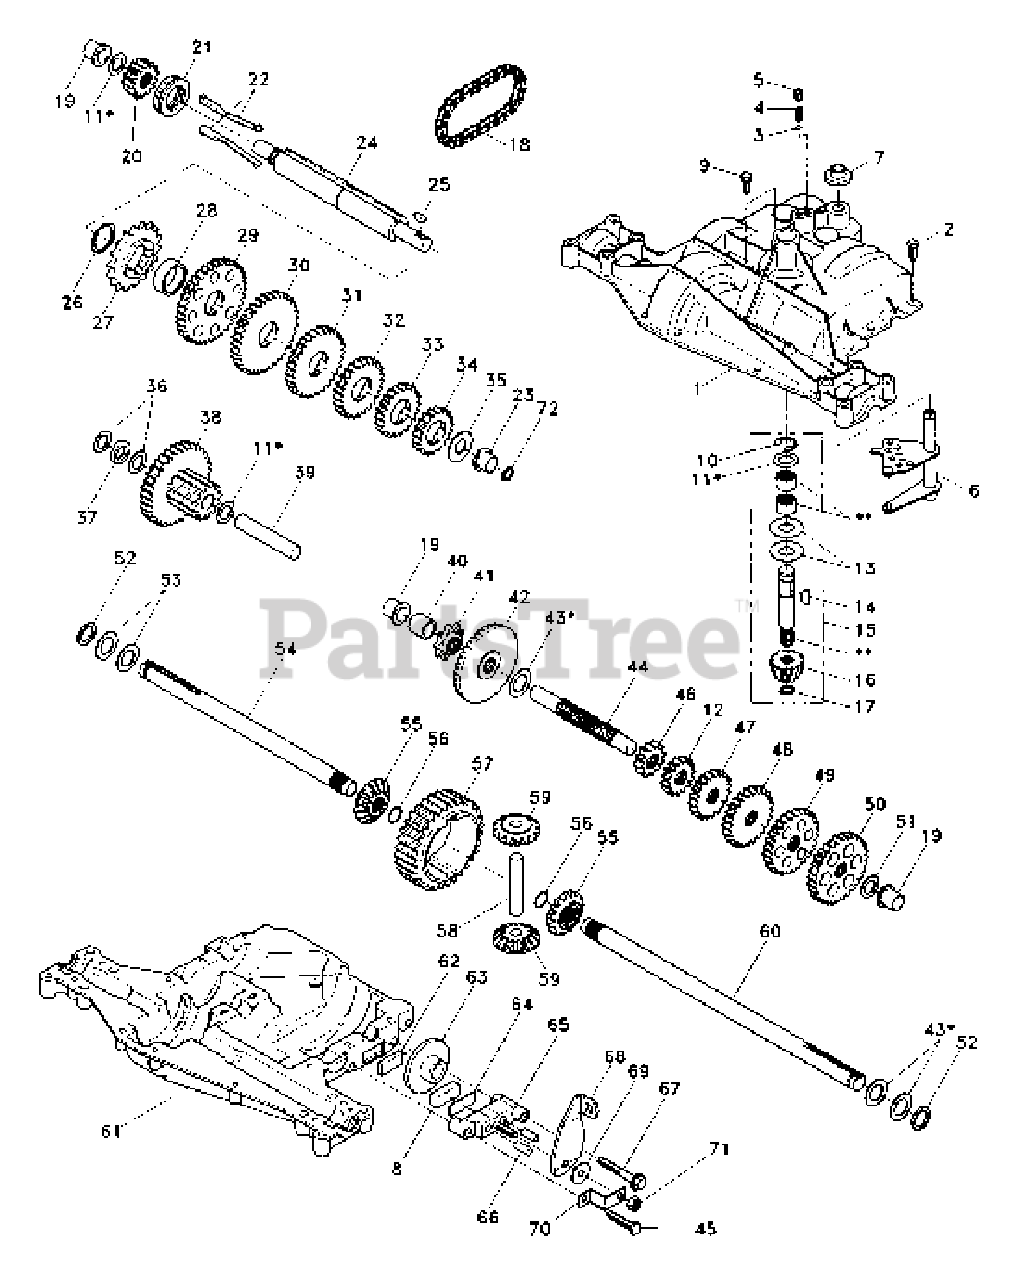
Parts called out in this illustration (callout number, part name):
1	Housing, Upper
2	Screw, Self-Tapping, Large 1/4-20 x .734
3	Ball, Detent
4	Spring, Detent
5	Screw, Set
6	Kit, Shifter Assembly
7	Boot, Shifter
8	Puck, Friction
9	Screw, Self-Tapping, with Sealer
10	Ring, Retaining
11	Assembly, Kit, Shim .625 Shaft
12	Gear, Spur, 15 Teeth
13	Washer, Plain .632 x 1.38 x .046
14	Key, Woodruff, #9
15	Assembly, Kit, Input Shaft
16	Pinion, Bevel, 14 Teeth
17	Ring, Retaining
18	Chain, 24 Pitches
19	Bearing, Flange
20	Gear, Spur, 14 Teeth
21	Collar, Clutch
22	Assembly, Kit, Clutch Keys
23	Bearing, Flange
24	Shaft, Intermediate
25	Key, Woodruff, #61
26	Ring, Retaining
27	Sprocket, 18 Teeth
29	Gear, Spur, 37 Teeth
30	Gear, Spur, 35 Teeth
31	Gear, Spur, 30 Teeth
32	Gear, Spur, 25 Teeth
33	Gear, Spur, 22 Teeth
34	Gear, Spur, 19 Teeth
35	Washer, Plain .640 x 1.37 x .061
36	Washer, Plain .632 x 1.00 x .026
37	Spacer .630 x 1.00 x .169
38	Assembly, Gear, Combination of 12 Teeth and 35 Teeth
39	Shaft, Idler
40	Spacer .635 x .875 x .755
41	Sprocket, 9 Teeth
42	Gear, Bevel, 42 Teeth
43	Assembly, Kit, Shim .750 Shaft
44	Shaft, Drive
45	Screw, Self-Tapping, Large 5/16-18 x 1.44
46	Gear, Spur, 12 Teeth
47	Gear, Spur, 20 Teeth
48	Gear, Spur, 25 Teeth
49	Gear, Spur, 28 Teeth
50	Gear, Spur, 31 Teeth
51	Washer, Plain .632 x 1.00 x .060
52	Washer, Neoprene
53	Washer, Plain .758 x 1.25 x .031
54	Axle, L.H.
55	Gear, Miter, 15 Teeth
56	Ring, Retaining
57	Gear, Spur, 32 Teeth
58	Shaft, Cross
59	Gear, Miter, 15 Teeth
60	Axle, R.H.
61	Housing, Lower
62	Puck, Friction
63	Disc, Brake
65	Jaw, Brake
66	Pin, Dowel
67	Screw, Self-Tapping, Large 5/16-18 x 2.25
68	Lever, Actuating
69	Washer, Plain .321 x 1.00 x .055
70	Bracket, Anti-Rotation
71	Locknut 5/16-24
73	Grease
